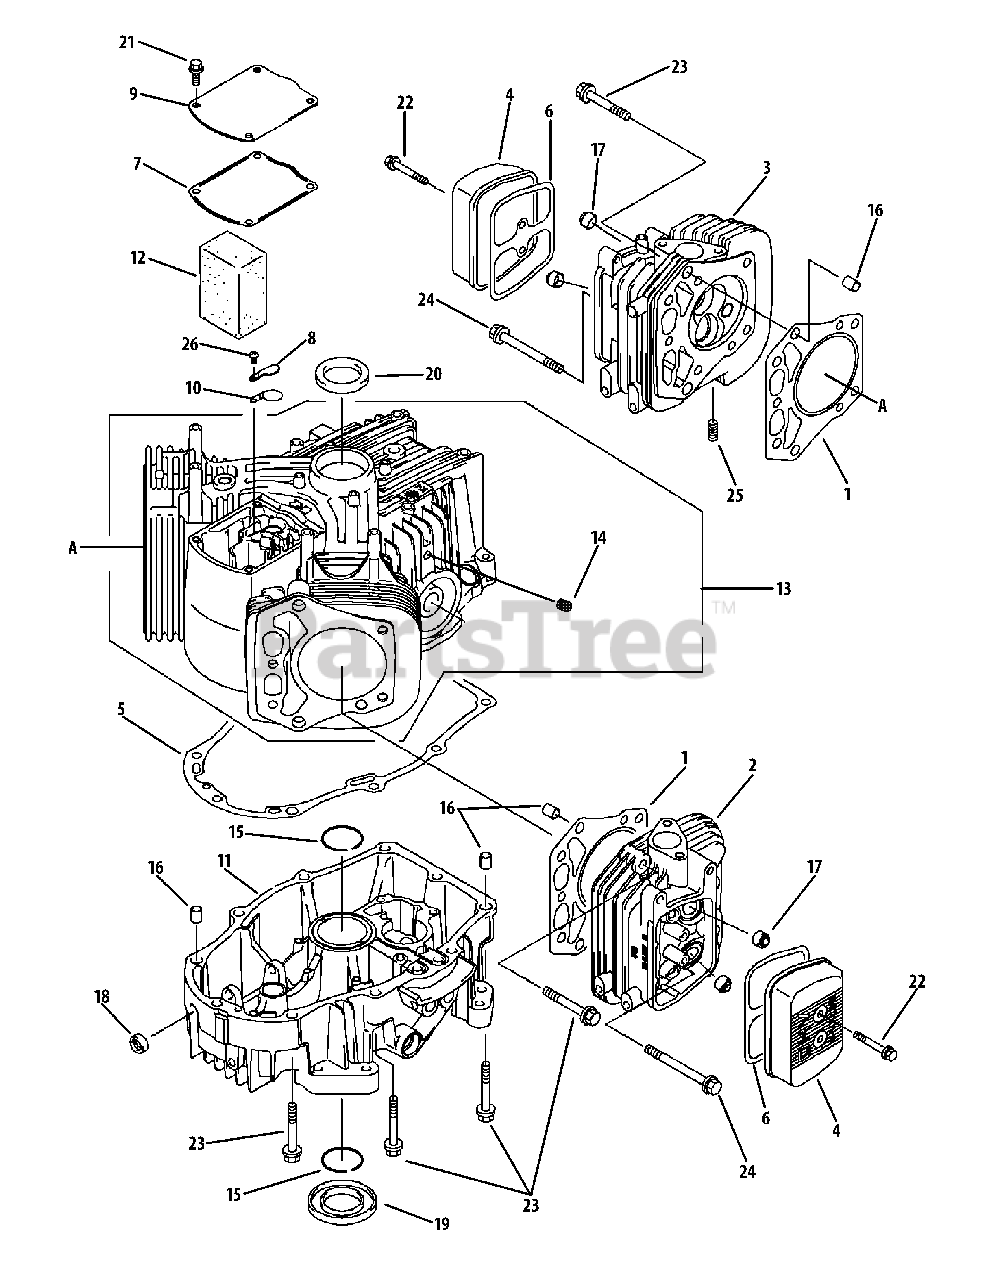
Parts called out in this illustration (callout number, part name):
2	Complete Cylinder Head, #2
3	Complete Cylinder Head, #1
4	Rocker Case
5	Crankcase Cover Gasket
6	Rocker Case Gasket
7	Breather Gasket
11	Crankcase Cover
12	Breather Element
13	Crankcase Complete
17	Oil Seal, RVC2 6 x 11 x 10.2
18	Oil Seal, SO 8 x 14 x 5 HS
19	Oil Seal, SD 35 x 62 x 8 L HS
20	Oil Seal, SD 35 x 52 x 7 R HS
21	Bolt
26	Pan Screw
